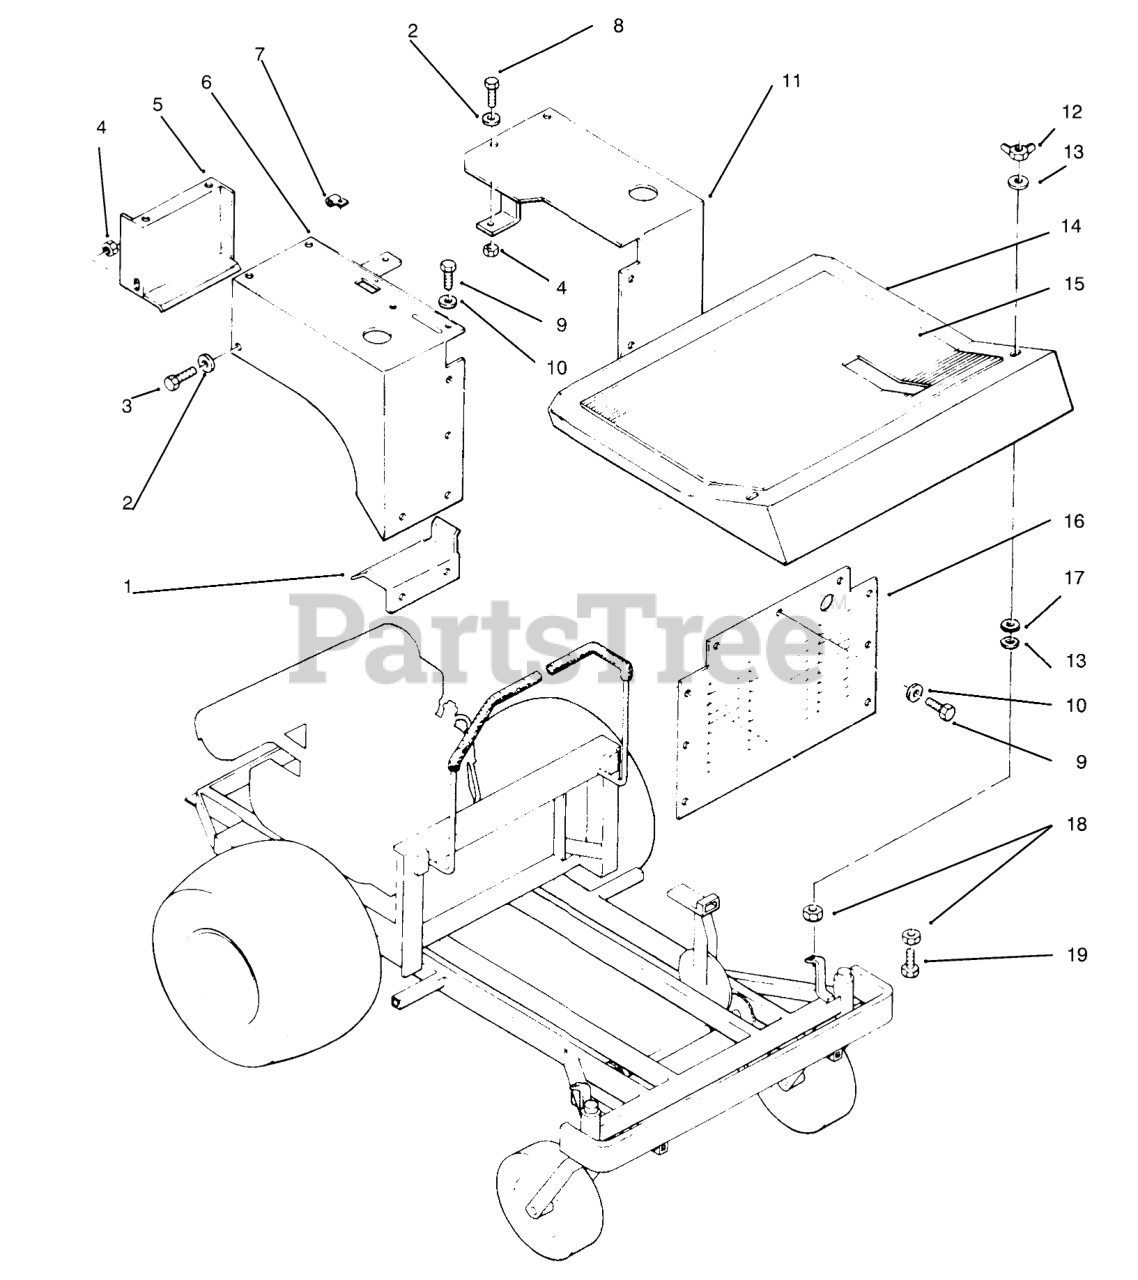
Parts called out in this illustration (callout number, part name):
1	Bracket-Fender Frt RH
2	WASHER-FLAT
3	SCREW-HH
4	NUT-LOCK, NI
5	Bracket-Fender Rear RH
6	FENDER WA RH R
7	J-CLIP
8	SCREW-HH
9	SCREW-HWH
10	WASHER-FLAT
11	Fender LH
12	WING NUT
13	WASHER-FLAT
14	Floor Pan
15	MAT - FOOTREST
16	Front Panel
17	WASHER
18	NUT-HEX
19	SCREW-HH
